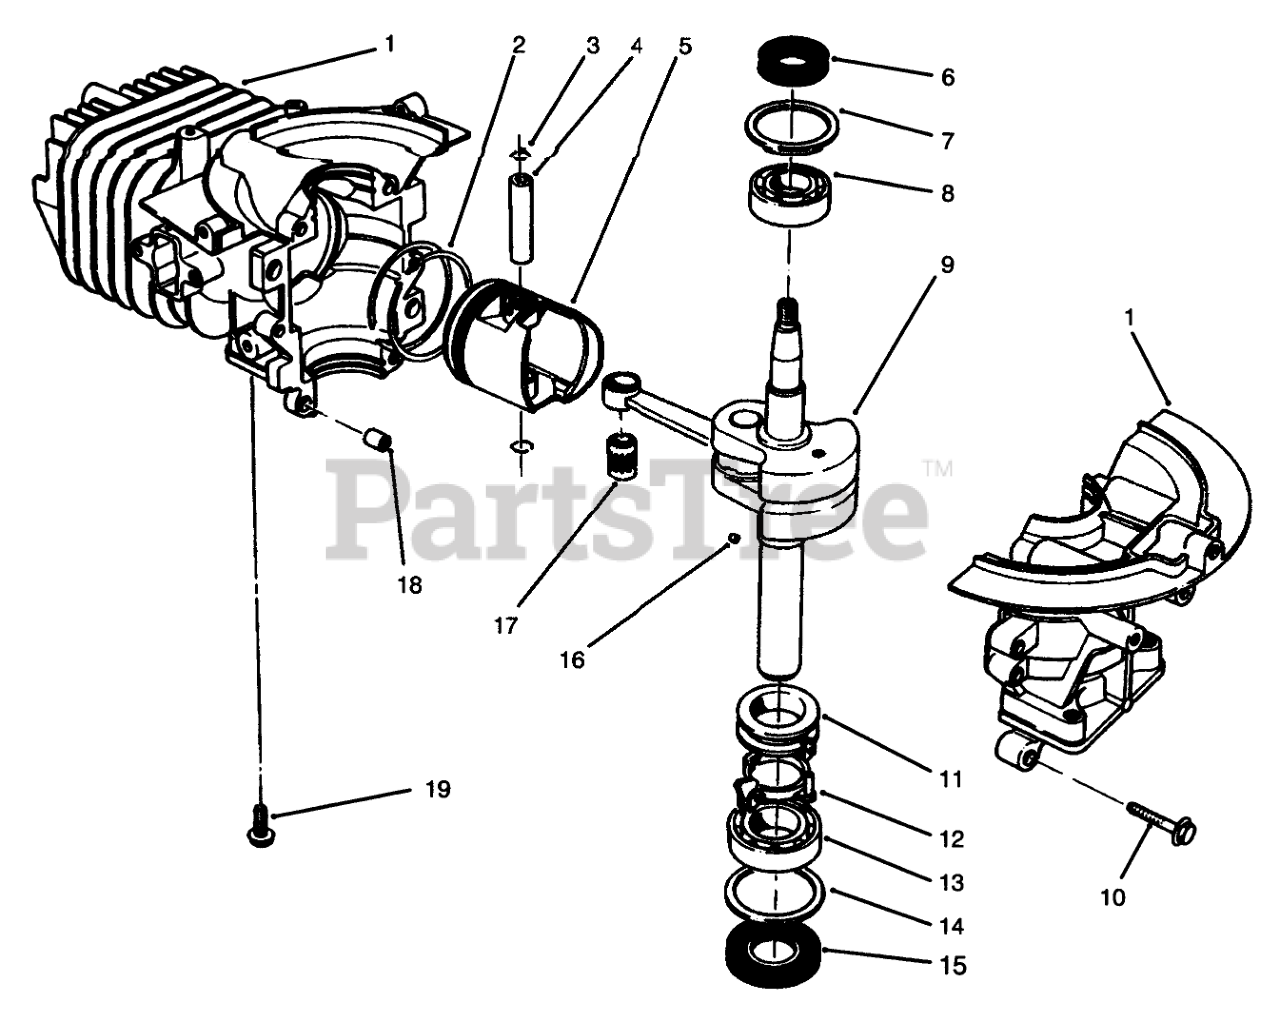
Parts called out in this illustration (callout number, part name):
1	CYLINDER/CRANKCASE
2	RING SET
4	HOUSING - CYL AIR, LH
5	PISTON
6	OIL SEAL
7	WASHER-UPPER
8	BEARING-UPPER
9	CRANKSHAFT
11	SPACER
12	BRACKET
13	LOWER BRG
14	WASHER-LOWER
15	SEAL-OIL
17	BEARING
